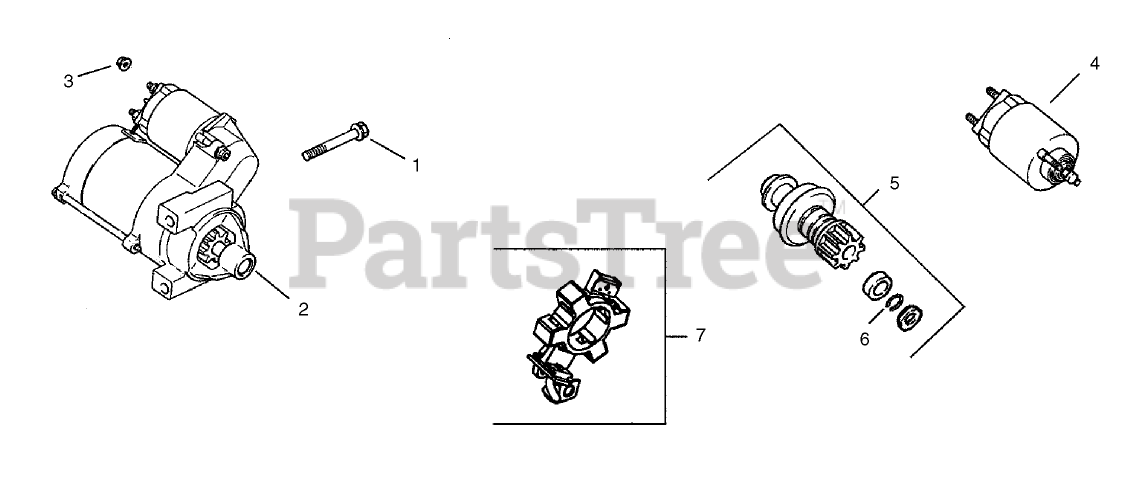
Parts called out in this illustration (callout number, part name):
1	SCREW-FLG (M8X1.25X80)
2	Starter, solenoid shift asm (Includes 4-7)
3	NUT-FLANGE (M8X1.25)
4	Solenoid Kit
5	Kit, pinion drive (Includes 6)
6	RING-RETAINING
7	BRUSH HOLDER KIT
